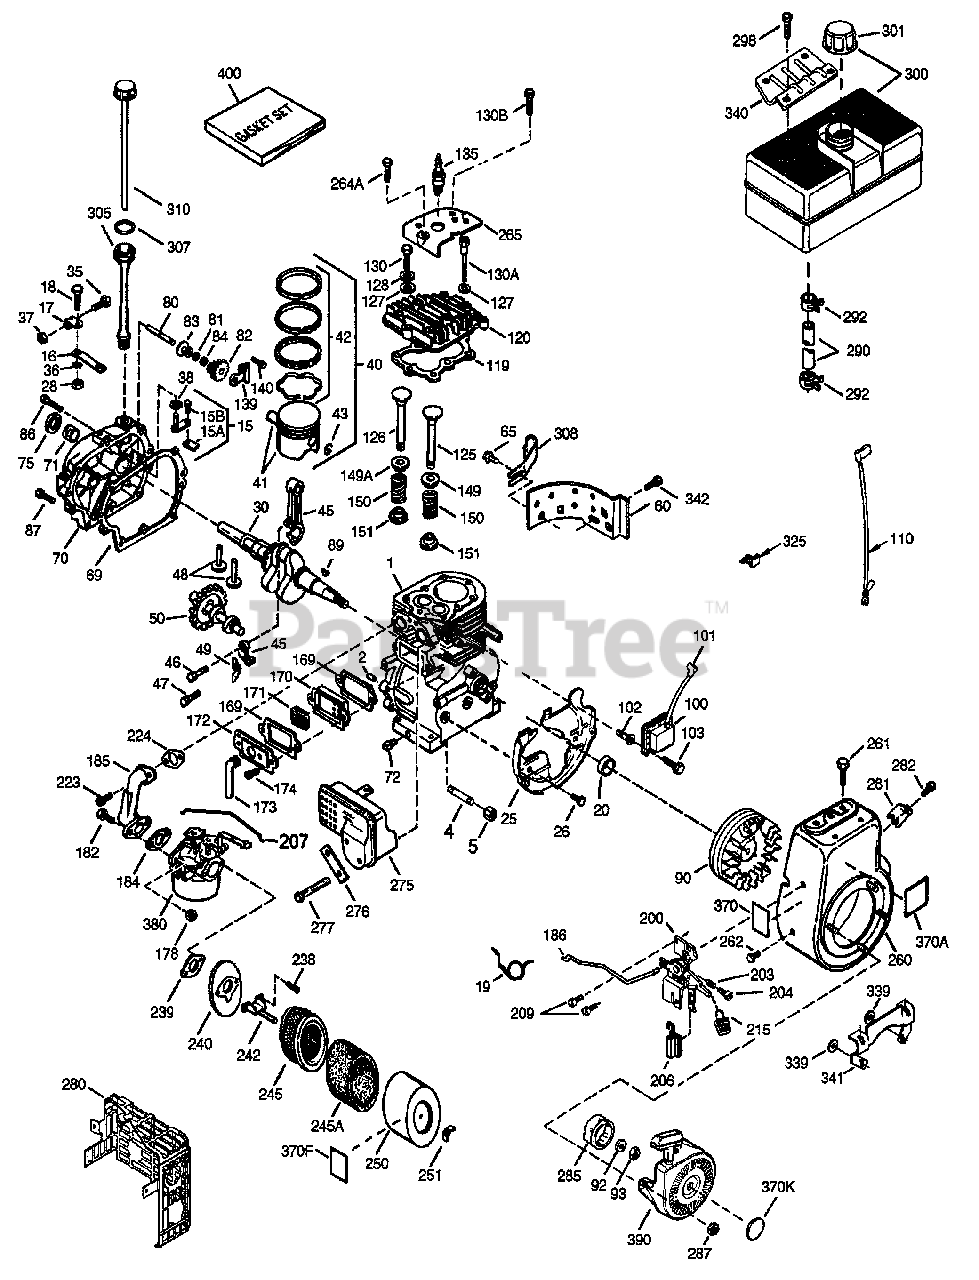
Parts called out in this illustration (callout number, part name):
2	Dowel Pin
4	Oil Drain Extension
5	Extension Cap
15	Governor Rod
15A	Governor Yoke
15B	Screw, 6-40 x 5/16"
16	Governor Lever
17	Governor Lever Clamp
18	Screw, 8-32 x 5/16"
19	Speed Control Spring
25	Blower Housing Baffle
26	Screw, 1/4-20 x 5/8"
28	Lock Nut, 8-32
30	Crankshaft
35	Screw, 10-32 x 3/4"
36	Lock Washer
37	Lock Nut, 10-32
38	Retaining Ring
40	Piston, Pin & Ring Set (Std)
41	Piston & Pin Assy (Std)
42	Ring Set (Std)
43	Piston Pin Retaining Ring
45	Connecting Rod Assy
46	Connecting Rod Bolt
47	Connecting Rod Bolt
48	Valve Lifter
49	Oil Dipper
50	Camshaft (MCR)
60	Blower Housing Extension
65	Screw, 10-24 x 1/2"
69	Cylinder Cover Gasket
70	Cylinder Cover
71	Crankshaft Bushing
72	Oil Drain Plug
80	Governor Shaft
82	Governor Gear Assy
83	Governor Spool
84	Retaining Ring
86	Screw, 1/4-20 x 1-3/16"
87	Screw, 1/4-20 x 1-11/16"
89	Flywheel Key
92	Lock Washer
93	Flywheel Nut
100	Solid State Ignition
101	Spark Plug Cover
102	Solid State Mounting Stud
103	Screw, Torx T-15, 10-24 x 15/16"
110	Ground Wire
119	Cylinder Head Gasket
120	Cylinder Head
125	Exhaust Valve (Std)
126	Intake Valve (Std)
128	Belleville Washer
130	Screw, 5/16-18 x 2"
130A	Screw, 5/16-18 x 1-3/4"
130B	Screw, 5/16-18 x 5/8"
135	Resistor Spark Plug
139	Governor Gear Bracket
140	Screw, 10-24 x 1/2"
149	Valve Spring Cap
149A	Valve Spring Cap
150	Valve Spring
151	Valve Spring Keeper
169	Valve Cover Gasket
170	Breather Body
171	Breather Element
172	Valve Cover
173	Breather Tube
174	Screw, 10-24 x 1/2"
178	Nut & Lock Washer, 1/4-28
182	Screw, 1/4-28 x 1"
184	Carburetor to Intake Pipe Gasket
185	Intake Pipe
186	Governor Link
200	Control Bracket
203	Compression Spring
204	Screw, 5-40 x 7/16"
207	Throttle Link
209	Screw, 10-32 x 1/2"
215	Control Knob
223	Screw, Torx T-30, 5/16-18 x 1-1/8"
224	Intake Pipe Gasket
238	Screw, 10-32 x 1/2"
239	Air Cleaner Gasket
240	Air Cleaner Body
242	Air Cleaner Bracket
245	Air Cleaner Filter
245A	Air Cleaner Filter
250	Air Cleaner Cover
251	Wing Nut, 1/4-20
260	Blower Housing
261	Screw, 5/16-18 x 3/4"
262	Screw, Torx T-40, 5/16-24 x 21/32"
264A	Screw, 1/4-20 x 5/8"
265	Cylinder Head Cover
276	Locking Plate
277	Screw, 5/16-18 x 3-3/16"
280	Heat Shield
281	Starter Bubble Cover
282	Screw, 8-32 x 3/8"
285	Starter Cup
287	Nut & Lock Washer, 1/4-28
290	Fuel Line
292	Fuel Line Clamp
298	Screw, 1/4-15 x 3/4"
301	Fuel Cap
305	Oil Fill Tube
308	Fill Tube Clip
325	Wire Clip
340	Fuel Tank Bracket
341	Fuel Tank Bracket
342	Screw, 1/4-20 x 9/16"
370	Instruction Decal
370A	Throttle Decal
370F	Instruction Decal
370K	Starter Decal
380	Carburetor
390	Rewind Starter
400	Gasket Set
